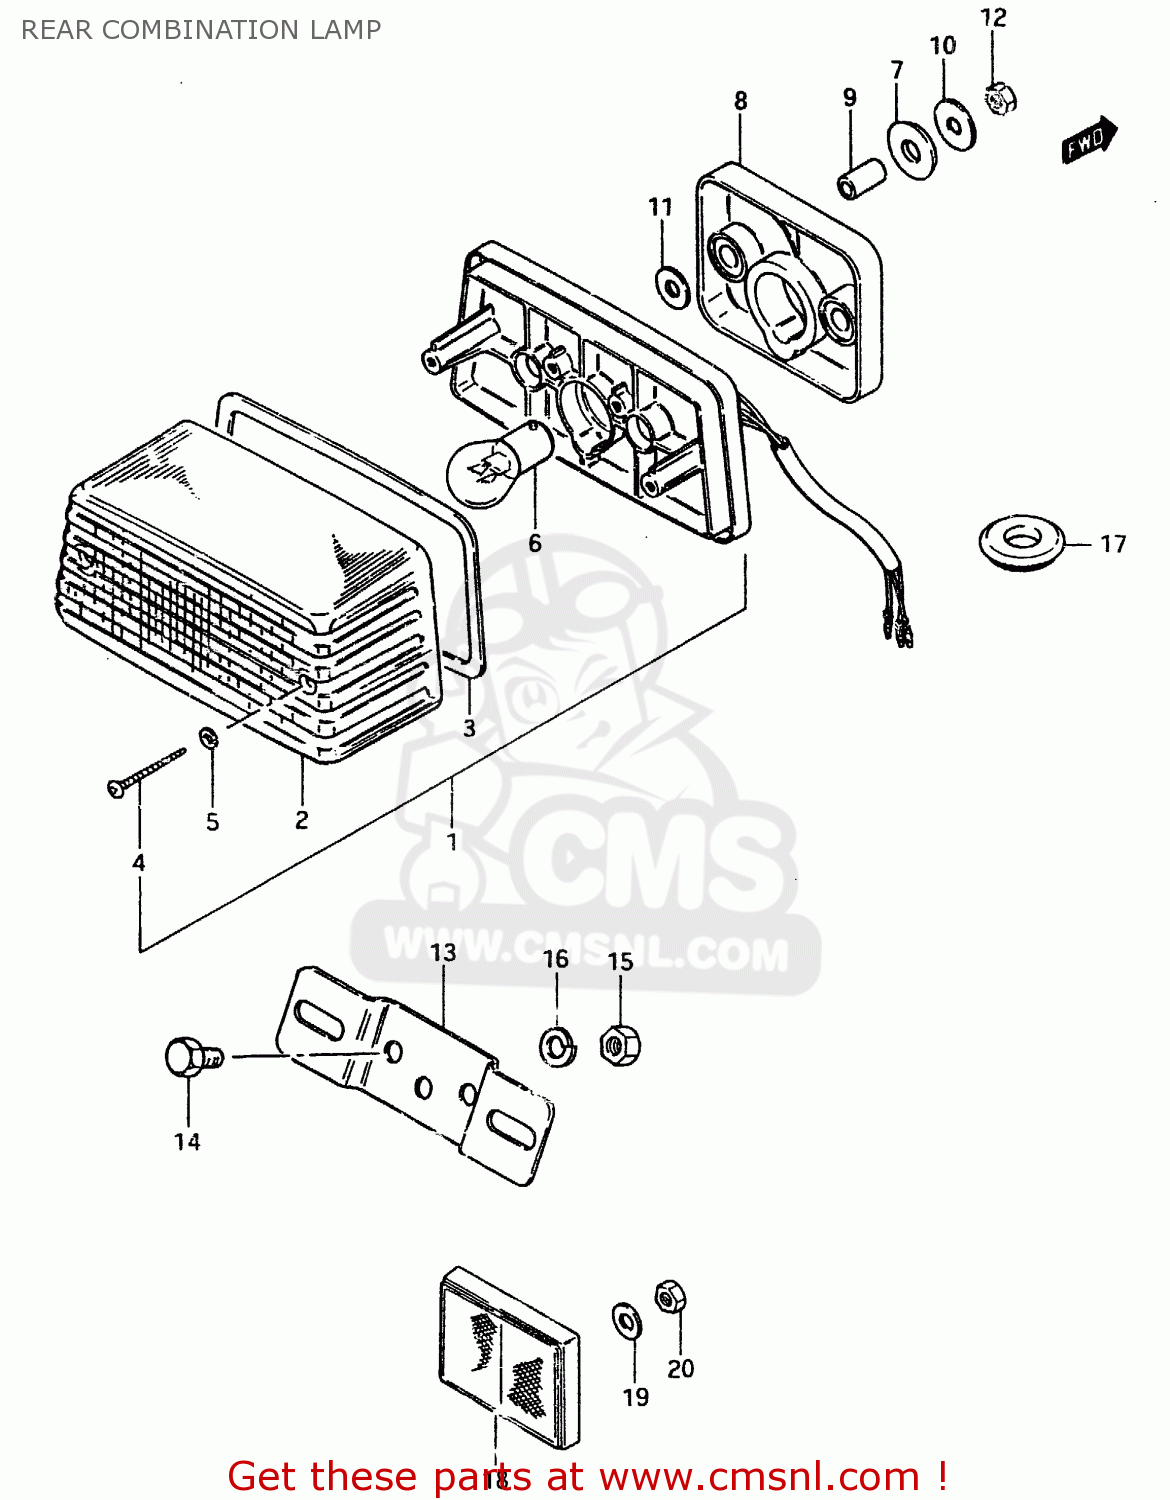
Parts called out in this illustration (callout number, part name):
1	LAMP ASSY, TAIL
2	LENS
3	GASKET (NAS)
4	SCREW
5	GASKET (NAS)
6	BULB (6V,21/5W)
7	CUSHION
8	CUSHION
9	SPACER
10	WASHER (5.5X20X1.2)
11	WASHER(5.2X16X1)
12	NUT
13	BRACKET, LICENSE PLATE
14	BOLT
15	NUT
16	LOCK WASHER
17	GROMMET
18	REFLEX REFLECTOR,RR
19	WASHER(5.2X16X1)
20	NUT
